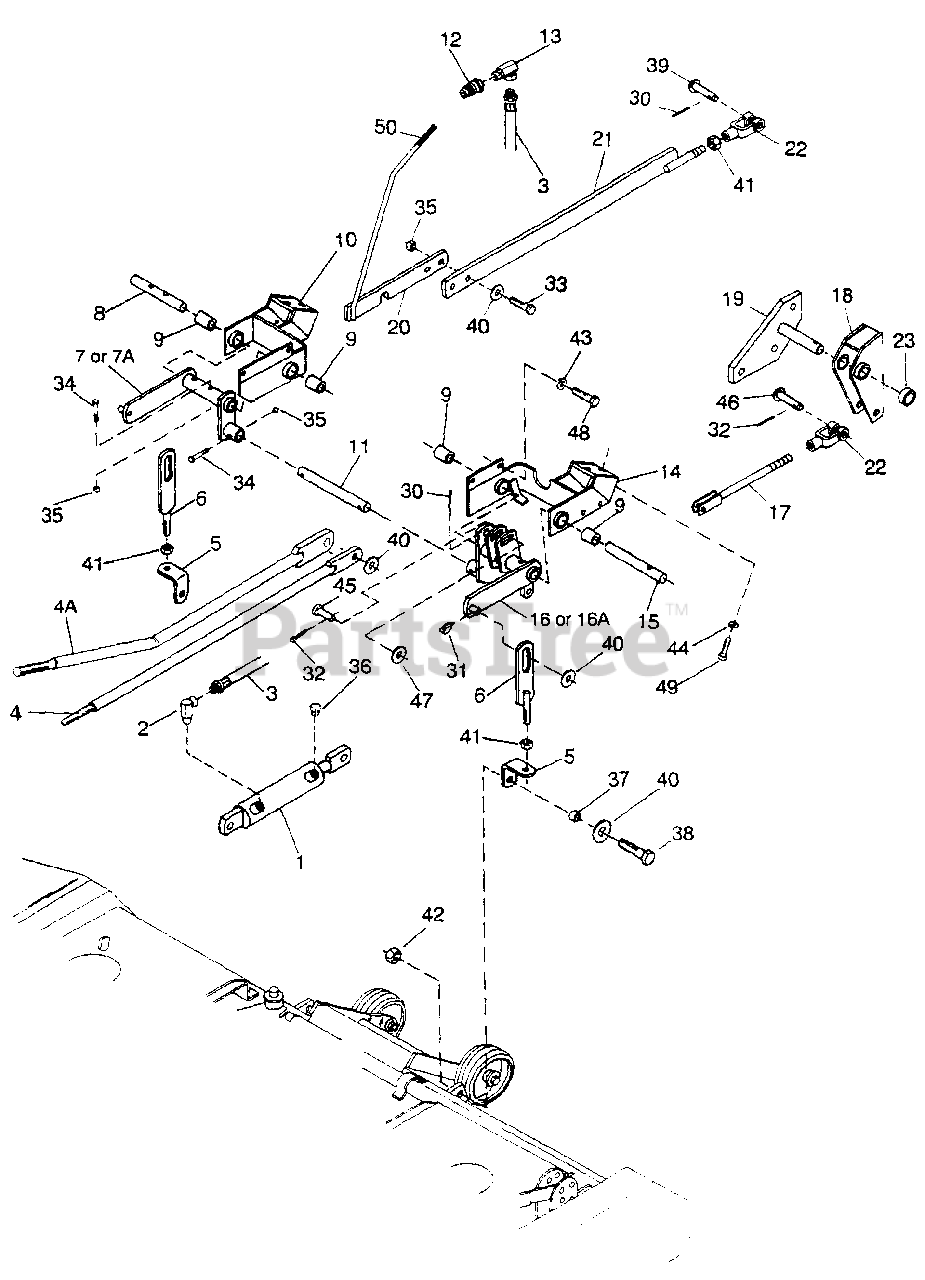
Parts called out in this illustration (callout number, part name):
1	Hydraulic lift cylinder
2	1/4 x 1/4 90° Swivel street elbow
3	1/4 NPT x 50 High-pressure hose assembly
4	Mower lift pull rod assembly
4A	Mower lift pull rod assembly
5	Lower lift link 1/2-13
6	Rear lift bar assembly
7	Right rear rockshaft assembly
7A	Right rear rockshaft assembly
8	Bar, drilled 1.0 dia. x 8.56
9	1.015 x 1.25 x 1 Oilite bushing
10	Right rear rockshaft mounting
11	Bar, drilled 1.0 x 10.31
12	Coupler, Male 1/2 NPT
13	1/2M x 1/4F 90° Swivel elbow
14	Left rear rockshaft mounting
15	Bar, drilled 1.0 dia. x 8.9
16	Left rear rockshaft assembly
16A	Left rear rockshaft assembly
17	Rear pull rod
18	Rear lift arm assembly
19	Lift mounting plate assembly
20	Lock-up bar
21	Lock-up extension
22	Adj. clevis yoke, .50-13 x 3.0
23	Bushing, 7/8 x 1 x 5/8
30	3/16 x 1 Cotter pin
31	3/16 x 1 Klik pin
32	3/16 x 1-1/2 Cotter pin
33	3/8 NC x 1-1/4 Hex head cap screw
34	3/8 NC x 1-1/4 Hex head cap screw GR5
35	3/8 NC Hex locknut
36	1/4 NPT Vent plug
37	1/2 x 3/4 x 1/2 Sleeve
38	1/2 NC x 1-1/2 Hex head cap screw GR5
39	1/2 x 1-3/4 Clevis pin
40	1/2 SAE Flat washer
41	1/2 NC Hex jam nut
42	1/2 NC Flanged hex locknut
43	1/2 NC Extra-heavy lockwasher
44	9/16 Standard lockwasher
45	5/8 x 1.65 Clevis pin
46	1/2 x 2-3/4 Clevis pin
47	5/8 Standard SAE flat washer
48	12mm x 1.75P x 25mm Hex head cap screw
49	14 mm x 2.0P x 30mm Hex head cap screw
50	Handle grip
